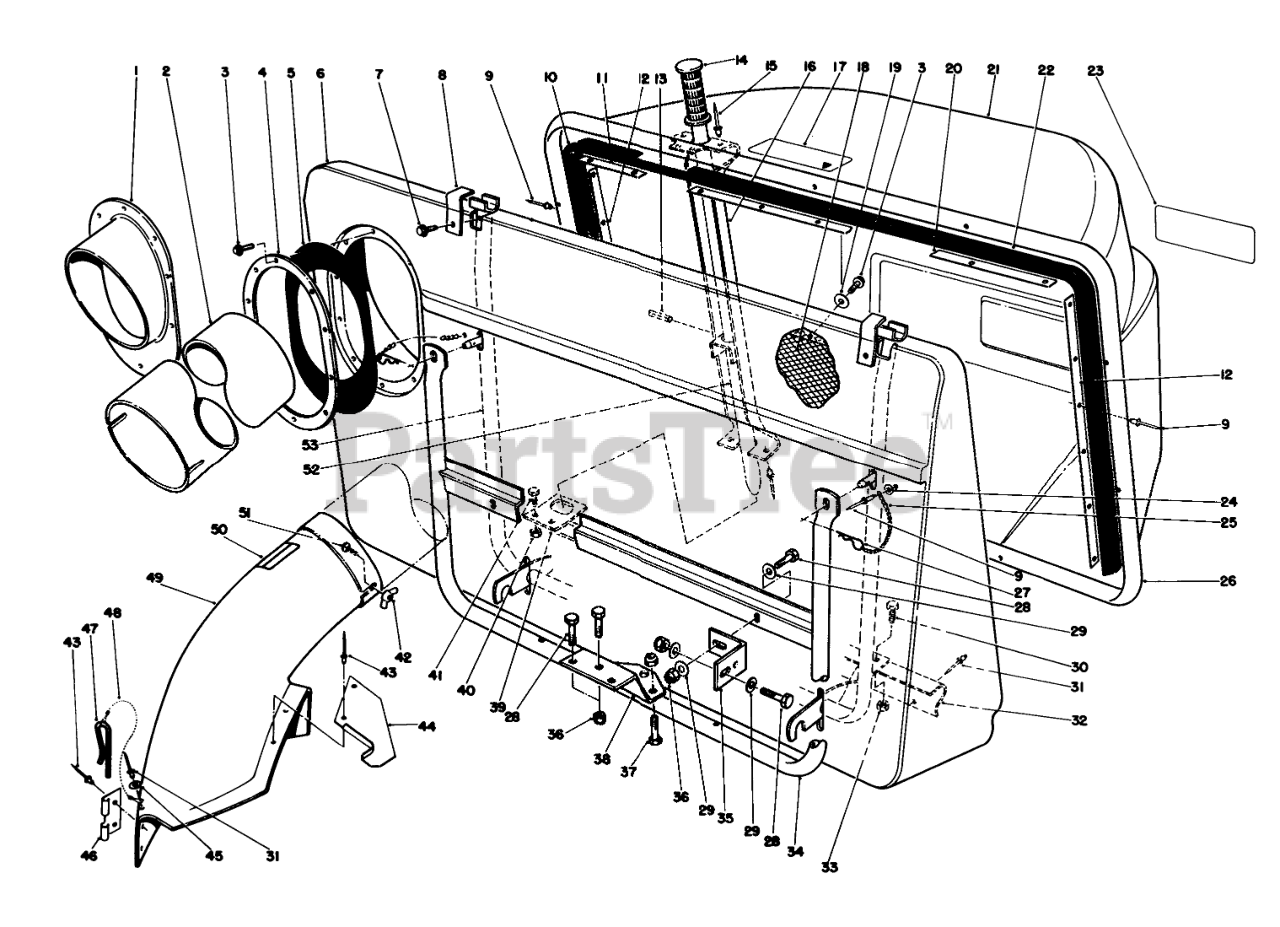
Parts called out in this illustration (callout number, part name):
1	DUCT ADAPTER
2	TUBE(ROUND&LONG)
3	SCREW-HWHTF
4	RING-RETAINING
5	RING-RETAINER, RUBBER
6	Bag Front
7	SCREW-HWH
8	RETNR PIVOT BRKT
10	RH BAG SEAL
11	RETNR TOP EXT.
12	BAG RETNR EXT.
13	PIN-ROLL
16	DUMP HDLE CHANL WA
17	Decal Warning
18	Screen Bag
19	WASHER-FLAT
20	EXTRUSION BAG RETAINER
21	REAR GRASS BASKET
22	Seal-Bag LH.
23	EASY EMPTY BAG DECAL
24	WASHER
25	10 LINK CHAIN W/O HOOK
26	BAG SUPT ASM FRM
27	PIN-HAIR
28	SCREW-HH
29	WASHER-PLAIN
30	SCREW-HH
31	RIVET-BLIND
32	FRAME SUPT BRKT B
33	NUT-LOCK, CONE
34	BAG SUPPORT WA
35	MTG BRACKET
36	NUT-LOCK, NI
37	SCREW-HH
38	MTG PLATE B
39	Hanger-Frame Lower
40	NUT-LOCK, CONE
41	SCREW-HH
42	NUT-WING SPECL
43	RIVET-BLIND
44	CHUTE SUPT BRKT
45	WASHER-PLAIN
46	BRACKET-MOUNTING, CHUTE
47	PIN-LOCKING, CHUTE
48	LANYARD
49	Chute Assembly (Incl. Ref. #31, 41-50)
50	DECAL-DANGER
51	BOLT-CARR
52	DUMP HANDLE ASM
53	Bag Frame
